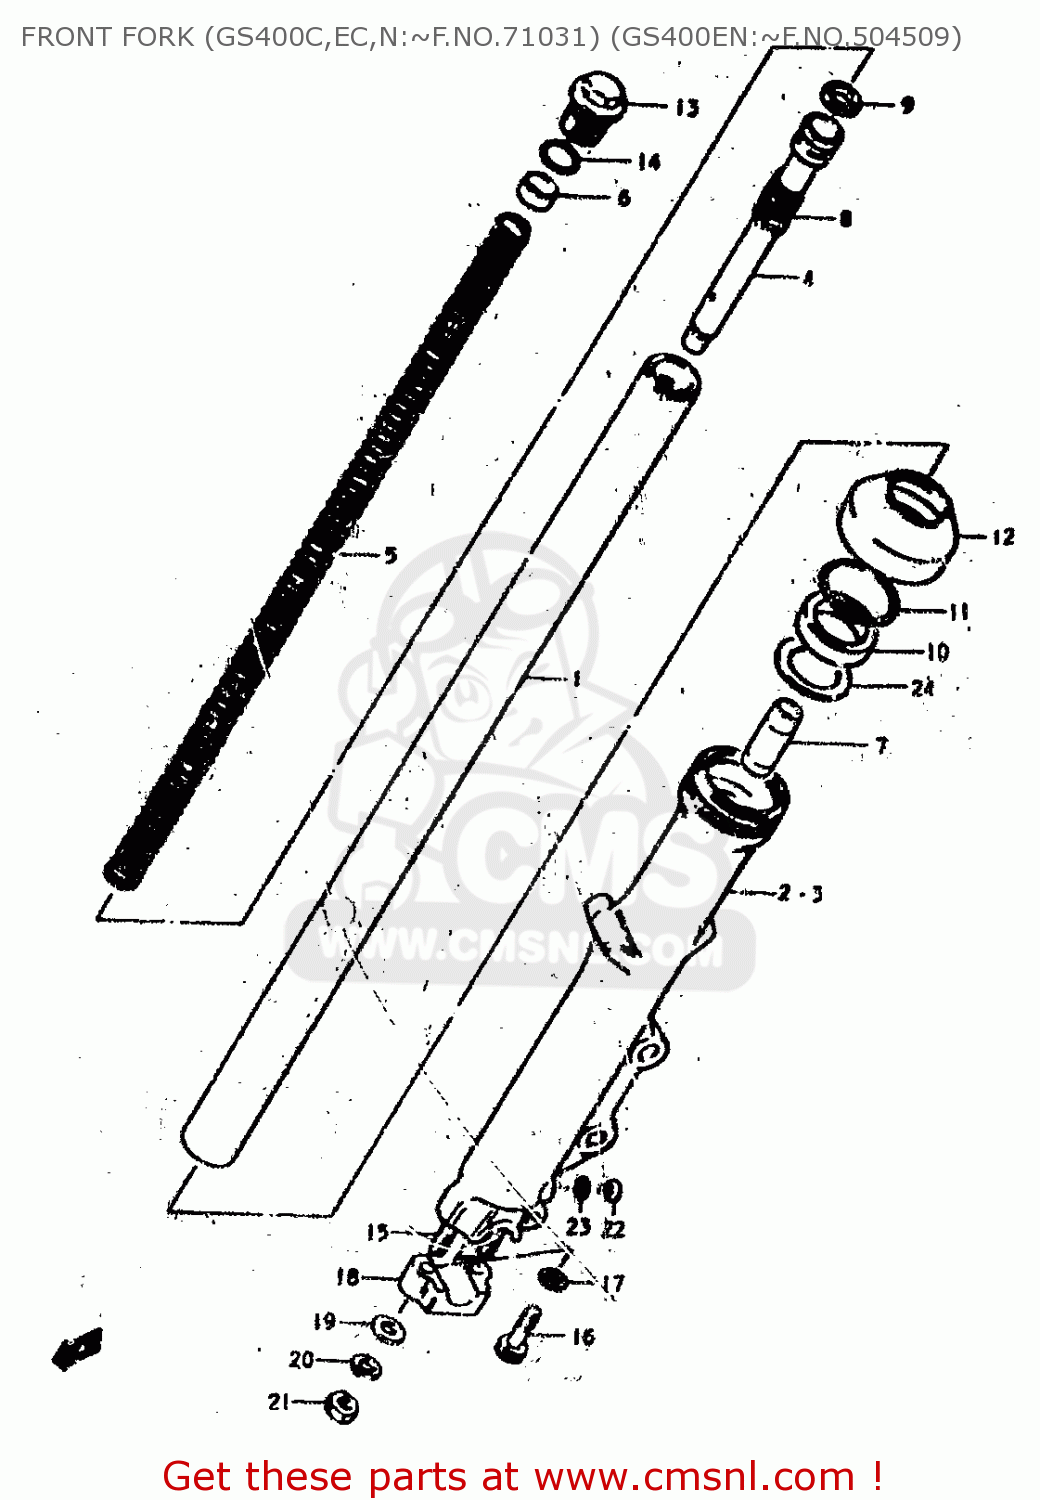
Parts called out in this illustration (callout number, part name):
1	TUBE,INNER
2	TUBE,FORK,LEFT,OUTER
3	TUBE,FORK,OUTER,RIGHT
4	CYLINDER,FRONT FORK
5	SPRING
6	SPACER,FRONT FORK SPRING
7	PIECE,OIL LOCK
8	SPRING,REBOUND
9	RING,PISTON
10	OIL SEAL,FRONT FORK
11	CIRCLIP,FORK OIL SEAL
12	BOOT
13	BOLT
14	O RING
15	STUD 8X25
16	BOLT
17	GASKET (NAS)
18	HOLDER,AXLE
19	WASHER
20	LOCK WASHER
21	NUT
22	SCREW
23	GASKET (NAS)
24	SPACER,OIL SEAL
